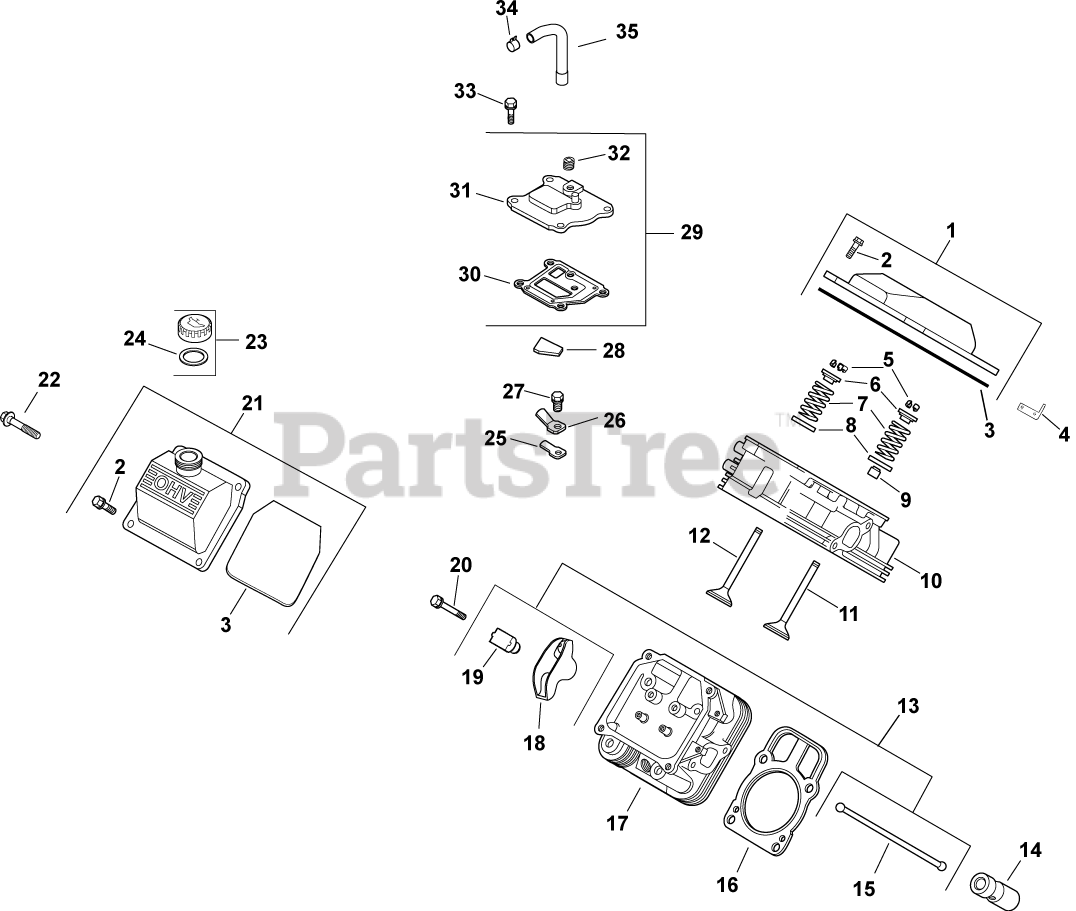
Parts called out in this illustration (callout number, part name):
1	KIT, VALVE COVER-PLAIN
2	SCREW, FLG M6X1.0X30
3	O-RING (YELLOW), VALVE COVER
4	STRAP, LIFTING-USE 25 445 03-S
5	KIT, RETAINER
6	RETAINER, VALVE SPRING - USE 25 173 28-S
7	SPRING, VALVE
8	RETAINER, SPRING
9	SEAL, VALVE STEM - (#2503214S)
10	KIT, #1 CYL HEAD ASSY-(#24318144S)
11	VALVE, INTAKE (STD)
12	VALVE, EXHAUST (STD) - USE 32 016 01-S
13	KIT, VALVE TRAIN
14	LIFTER, HYDRAULIC VALVE-USE 25 351 10-S
15	ROD, PUSH
16	KIT, CYL HEAD GASKET (C17-22)
17	HEAD, ASSEM CYLINDER #2 -USE 24 318 115-
18	ARM, ROCKER
19	PIVOT, ROCKER ARM
20	SCREW, FLG M6X1.0X34
21	KIT, VALVE COVER-OIL FILL
22	SCREW - USE 62 086 08-S
23	KIT, OIL FILL CAP (YELLOW)
24	O-RING, DIPSTICK
25	REED, BREATHER
26	RETAINER, REED
27	SCREW, FLG THD FRM M5X.8X10
28	FILTER, BREATHER
29	KIT, BREATHER ASSEMBLY
30	GASKET, BREATHER-USE 24 041 67-S
31	COVER, BREATHER -USE 24 033 01-S
32	PLUG, CTSK PIPE 1/8"
33	SCREW,FLG THD FRM M6X1.0X20-(#25086396S)
34	CLAMP, HOSE (KM)-USE 25 237 31-S
35	HOSE, BREATHER
2401602-S	VALVE, EXHAUST (.25)
2401702-S	VALVE, INTAKE (.25)
24755147-S	KIT, CYLINDER HEAD HARDWARE
